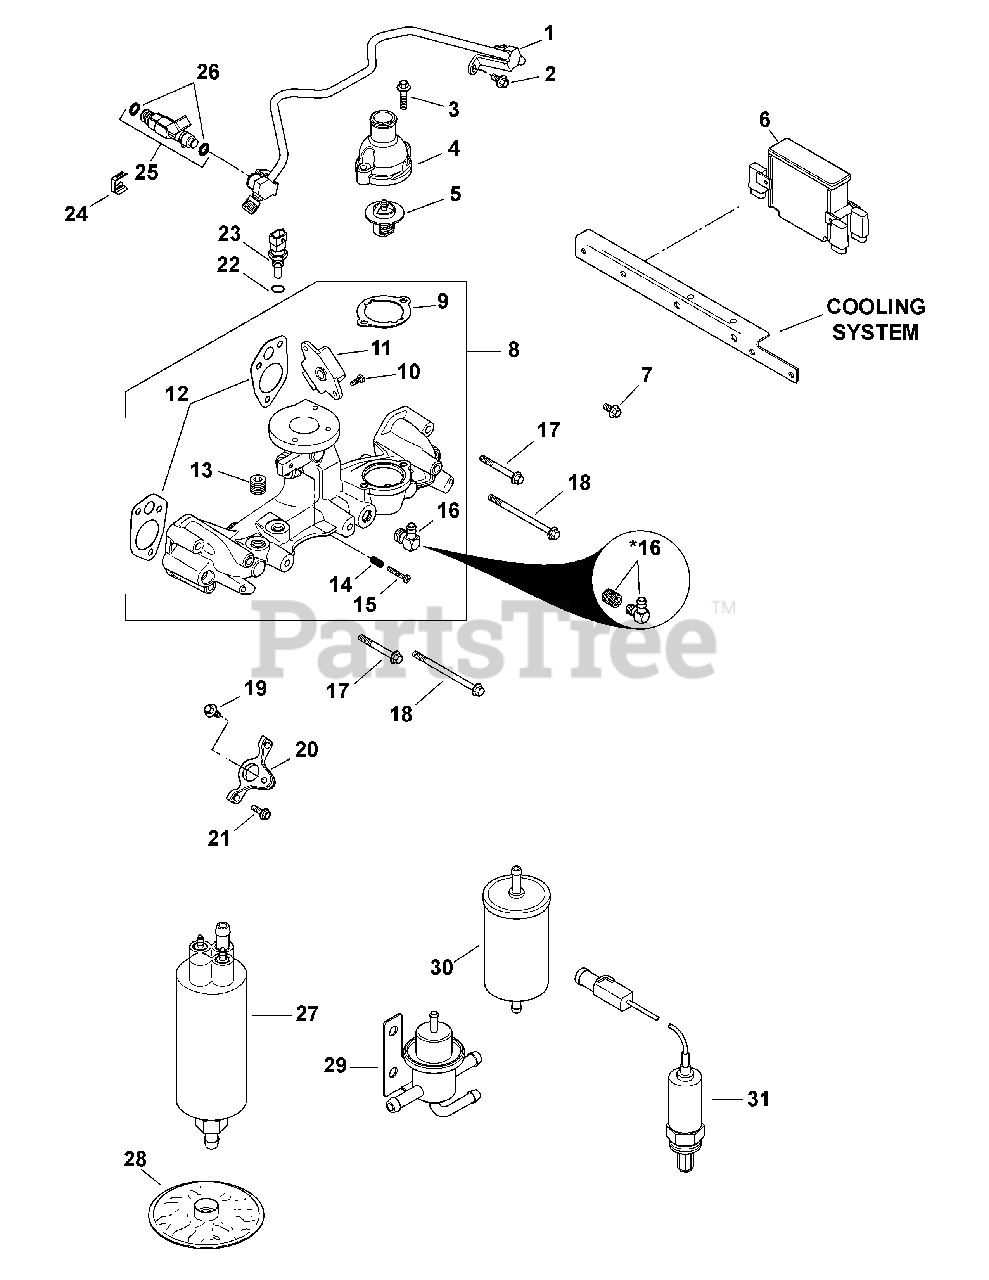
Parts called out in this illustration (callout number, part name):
2	SCREW, FLG M6X1.0X12
3	SCREW, FLG M6X1.0X25
4	HOUSING, THERMOSTAT
5	KIT, THERMOSTAT
6	MODULE, ENGINE MANAGEMENT (ECU)
7	SCREW, FLG M6X1.0X12
8	KIT, EFI INTAKE MANIFOLD
9	GASKET, THERMOSTAT
10	SCREW, PHL PAN M4X0.7X12
11	KIT, THROTTLE POSITION SENSOR
12	GASKET, INTAKE MANIFOLD
13	PLUG, PIPE CTSK 3/8"
14	SPRING, SPEED CONTROL (SHORT)
15	SCREW, PHL PAN M4X0.7X25
16	CONNECTOR, HOSE
17	SCREW, FLG M6X1.0X50
18	SCREW, FLG M6X1.0X90
19	SCREW, FLG THD FRM M6X1.0X16
20	BRACKET, SPEED SENSOR
21	SCREW, FLG THD FRM M5X0.8X16
23	SENSOR, TEMPERATURE
24	CLIP, FUEL INJECTOR
25	INJECTOR, FUEL
27	PUMP ASSY, FUEL
28	FILTER, FUEL STRAINER
29	REGULATOR ASSY, FUEL PRESSURE
31	SENSOR, OXYGEN
